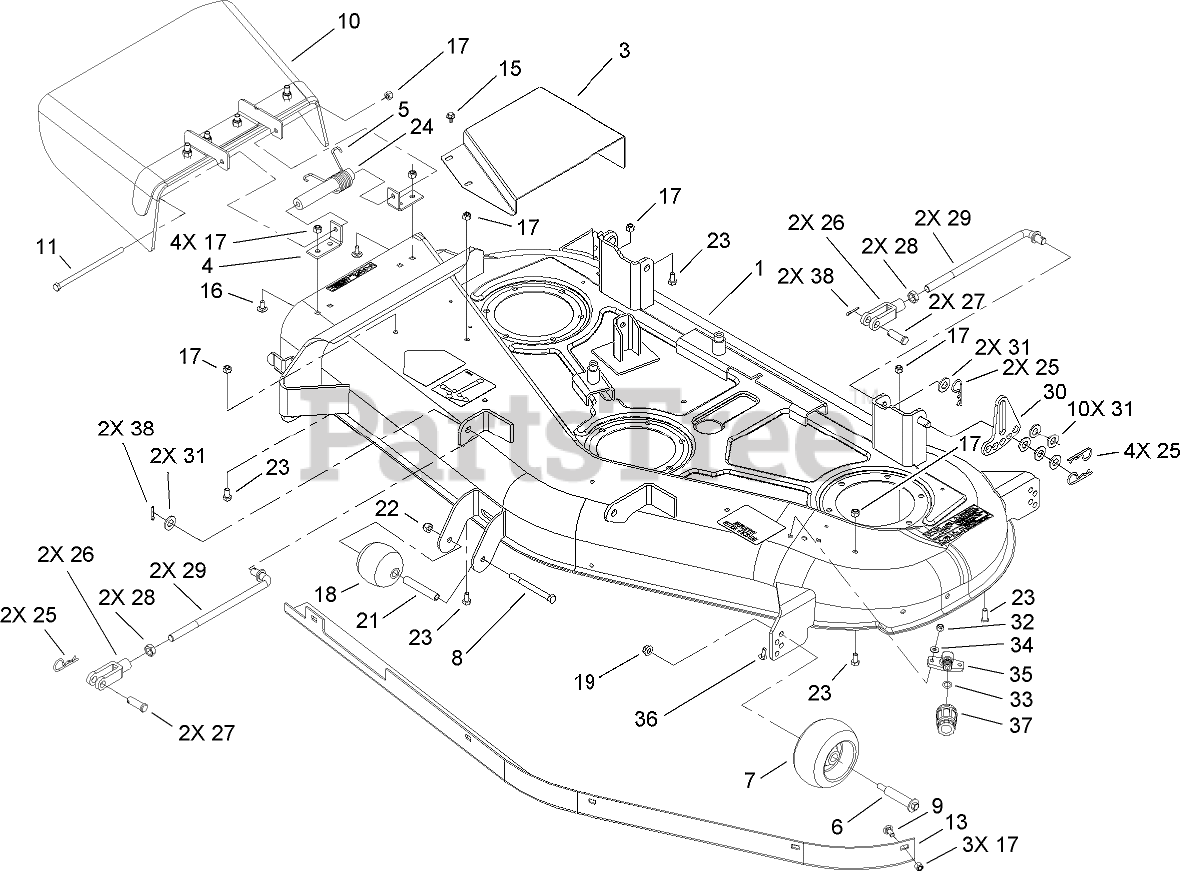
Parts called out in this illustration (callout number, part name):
1	52 INCH DECK ASM
3	COVER-BELT, RH
4	BRACKET-PIVOT, DEFLECTOR
5	SPRING-TORSION
6	BOLT-SHOULDER
7	ROLLER-SCALP, ANTI
8	SCREW-HH
9	SCREW-CARR
10	DEFLECTOR ASM
11	BOLT-HH
15	SCREW-HHFTF
16	SCREW-CARR
17	NUT-LOCK, NI
18	ROLLER
19	NUT-LOCK, NI
21	TUBE-SPACER, WHEEL
22	NUT-LOCK, NI
23	SCREW-HH
24	SPACER-DEFLECTOR
25	PIN-COTTER
26	CLEVIS
27	PIN-CLEVIS
28	NUT-JAM
29	ROD-TRUNION
30	LINK-HOC, ADJUSTING
31	WASHER-FLAT
32	NUT-LOCK, NI
33	O-RING
34	WASHER-FLAT
35	FITTING-WASHOUT
36	BOLT-CARR
37	CONNECTOR-HOSE
38	PIN-COTTER
